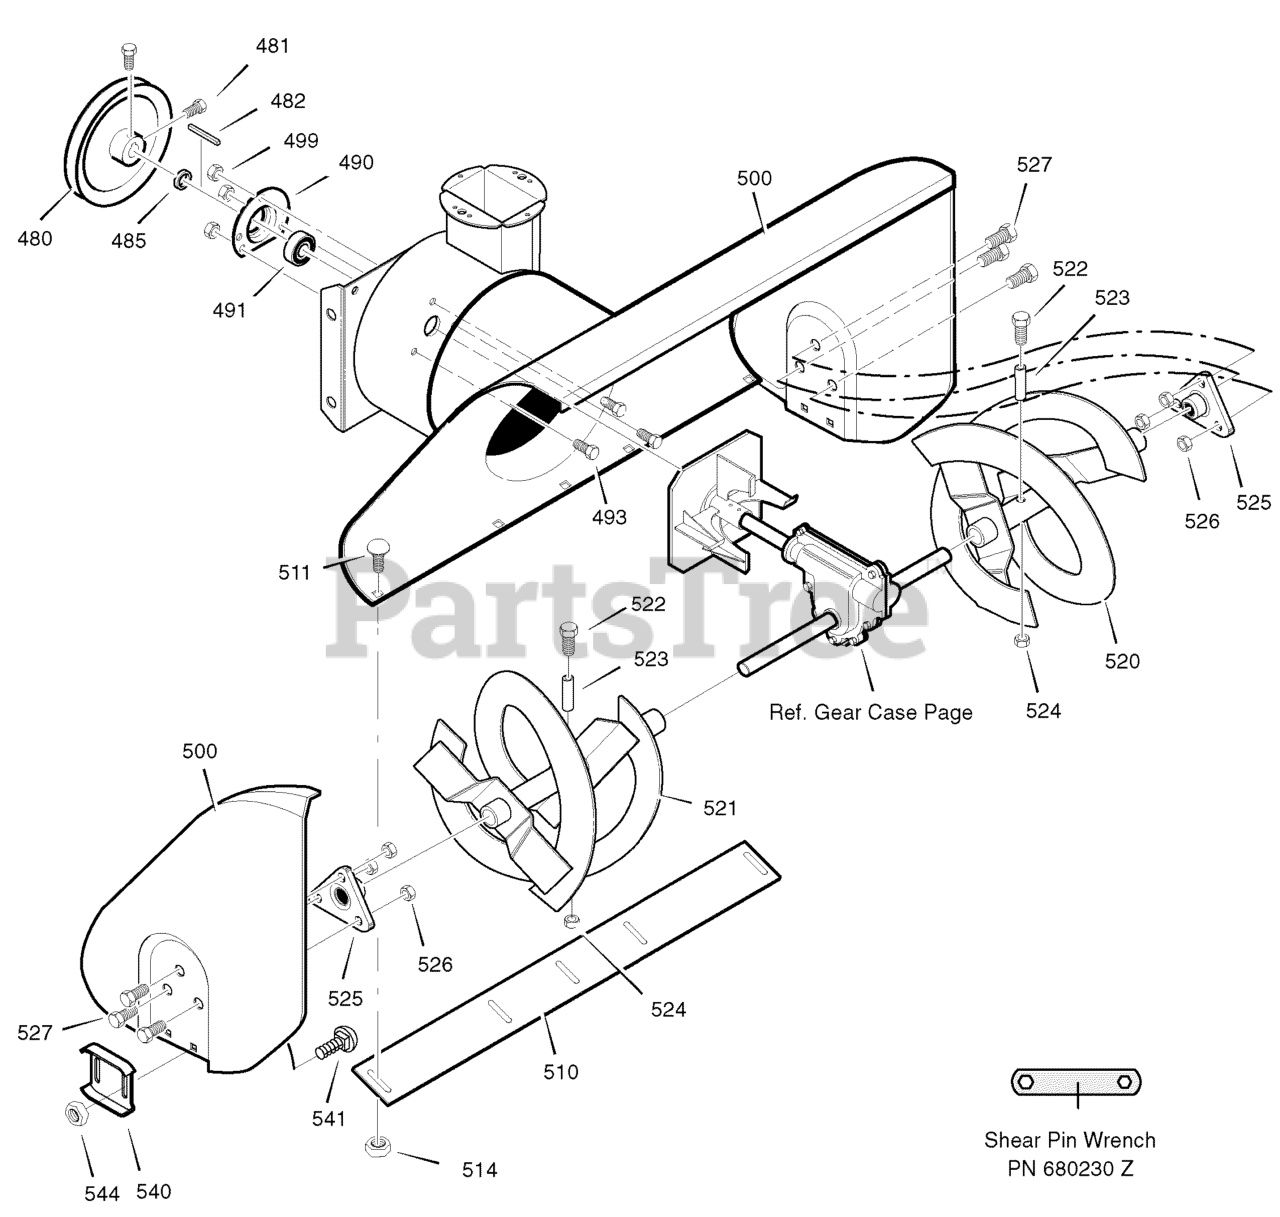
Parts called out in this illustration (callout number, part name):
480	PULLEY, 4L 6.12X .67
481	SCREW, 5/16-18 X .63
482	KEY, SQUARE 3/16 X 3/4
485	SPACER, FRICTION PULLEY
490	RETAINER, BALL BRNG
491	BEARING, BALL
493	BOLT, HEX 5/16-18X 0.50
499	NUT, 5/16-18 HEX
500	HOUSING, ASSY
510	BLADE, SCRAPER
511	BOLT, 1/4-20X.75
514	NUT, 1/4-20
520	AUGER, ASSY, LH
521	AUGER, ASSY, RH
522	SCREW, 1/4-20X1.75
523	SPACER, SLEEVE
524	NUT, 1/4-20
525	BEARING, FLANGE
526	NUT, 5/16-18
527	SCREW, 5/16-18 X .75
540	SKID, HEIGHT ADJUST
541	BOLT, 5/16-18 X .75
544	NUT, 5/16-18
